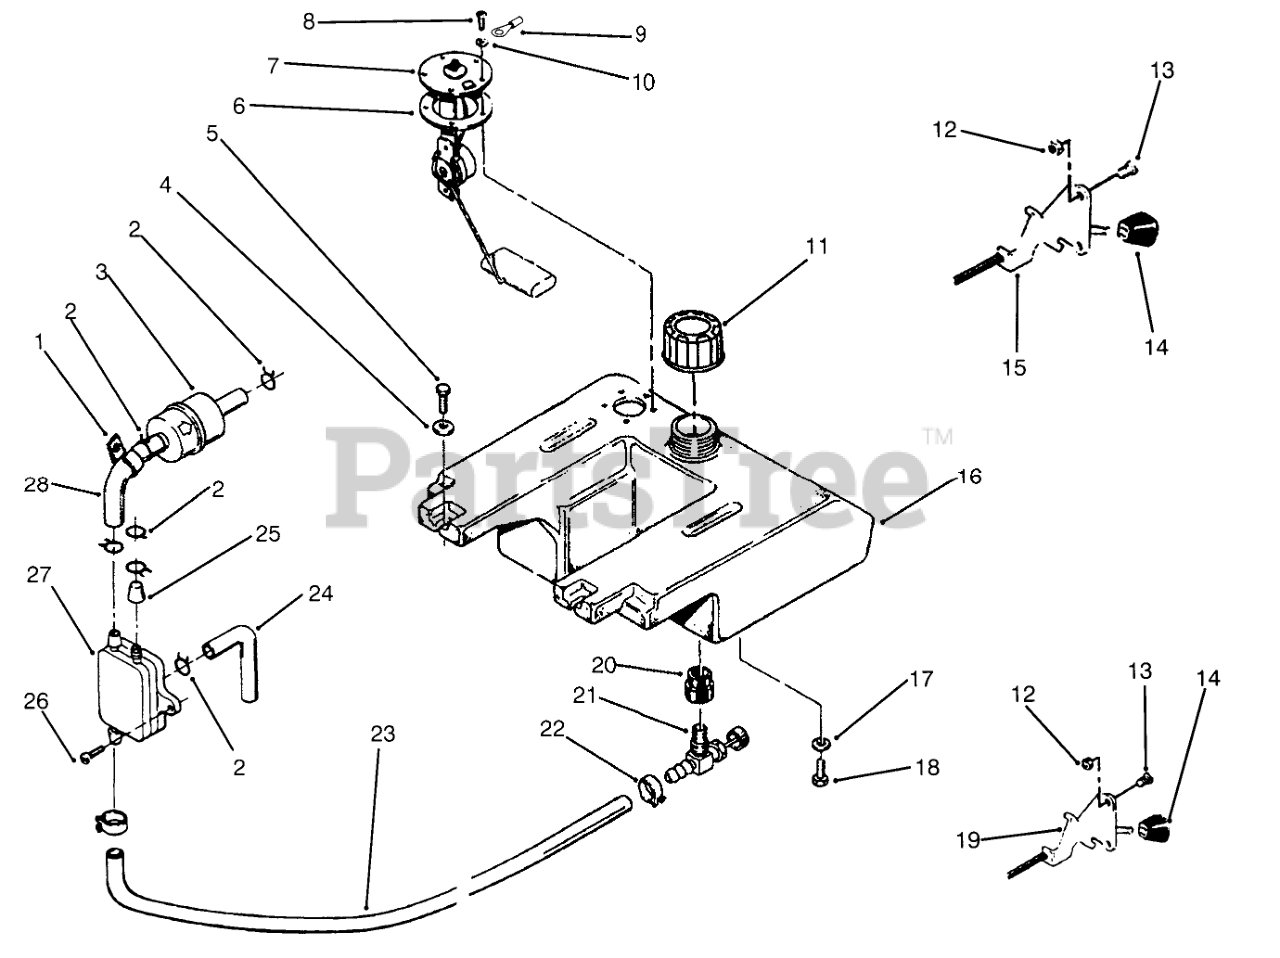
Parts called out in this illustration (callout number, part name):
1	Clip
2	CLAMP-HOSE
3	FILTER-FUEL
4	WASHER-FLAT
5	SCREW-HWHTF
6	GASKET-SENDER, FUEL
7	SENDER-FUEL LEVEL
8	Screw
9	TERMINAL-GROUND
10	WASHER-LOCK
11	GAS CAP ASM
12	Nut
13	Screw
15	CONTROL-THROTTLE
16	Tank-Fuel (Incl. Ref. #20-21)
17	WASHER-LOCK
18	SCREW-HH
19	CONTROL-CHOKE
20	BUSHING
21	VALVE-FUEL
22	CLAMP-HOSE
23	FUEL HOSE 75" OF 6554
24	Hose
25	CAP-FUEL OUTLET
26	SCREW-TAPPING PAN HD
27	PUMP-FUEL
28	FUEL HOSE
